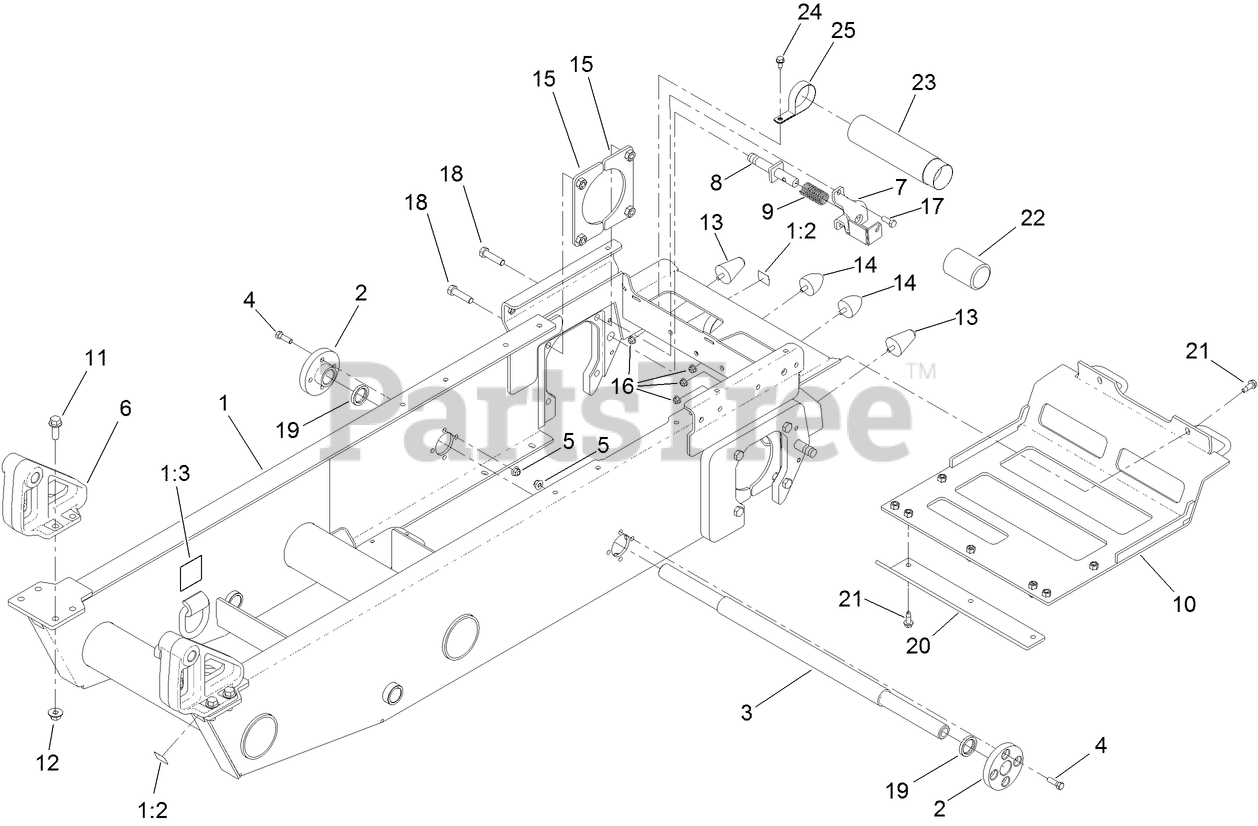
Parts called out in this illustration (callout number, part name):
1	FRAME ASM
1:2	DECAL-TIEDOWN
1:3	DECAL-LIFT HERE
2	HUB-SHAFT
3	SHAFT-TRACK
4	SCREW-HH
5	NUT-HF, NI
6	PIVOT-DUMP
7	BRACKET-BRAKE
8	SHAFT-BRAKE
9	SPRING-COMPRESSION
10	REAR SKID PLATE ASM
11	SCREW-HHF
12	NUT-LOCK, FLANGE
13	BUMPER-RUBBER
14	BUMPER-RUBBER
15	HYDRO MOUNTING PLATE ASM
16	NUT-HF, NI
17	SCREW-HH
18	SCREW-HH
19	SPACER-TRACK, INSIDE MOUNT
20	PLATE-SKID
21	Screw-Tapping
22	CAP-HOUSING
23	TUBE-MANUAL
24	SCREW-HWHTF
25	CLAMP-R
